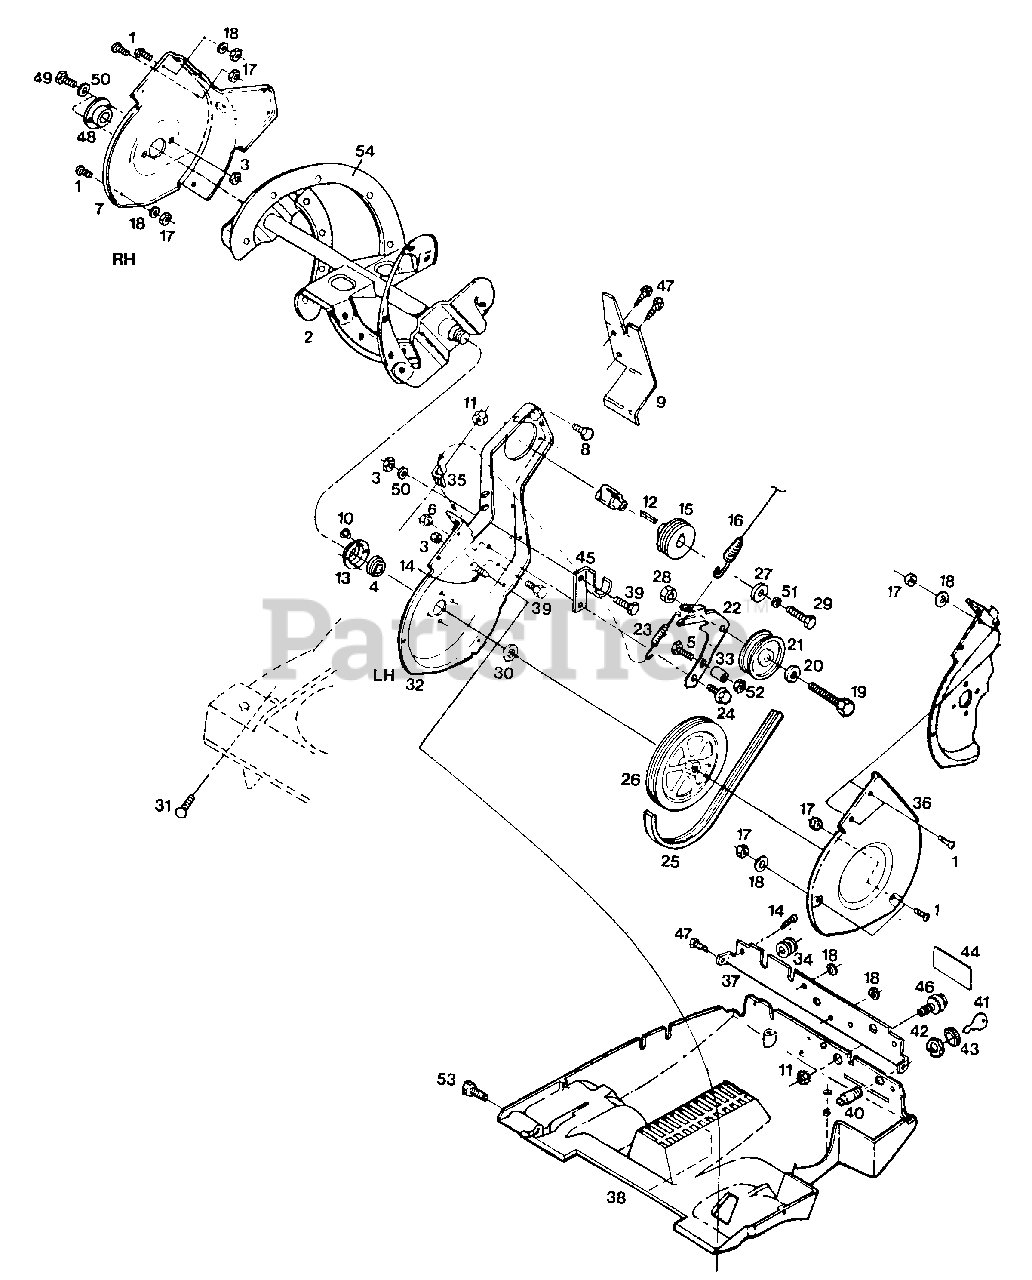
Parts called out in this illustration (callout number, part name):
1	SCREW - Phillips #10 - 24 x 5/8"
2	AUGER - Assembly
3	NUT - 1/4 - 20 Nylock
4	BEARING
5	BOLT - Hex 1/4 - 20 x 1
6	NUT, 5/16-18 Nylock
7	FRAME - Right Side
8	BOLT - Hex 5/16 - 24 x 5/8
9	SHIELD - Belt
10	RIVET - 1/4
11	NUT - Keps 1/4 - 20
12	KEY - 1865 Sq. x 1
13	RETAINER - Bearing
14	SCREW - H.W.H. Tap #10 - 24 x 3/4
15	PULLEY - Drive
16	CABLE - Auger Control
17	NUT - #10 - 24
18	WASHER - Retaining
19	BOLT - Hex 3/8 - 16 x 1-1/2
20	WASHER - Flat 3/8
21	PULLEY - Idler
22	ARM - Idler
23	SPRING - Extension
24	BOLT - Idler Pivot
25	BELT - Drive
26	PULLEY - Drive
27	WASHER - Flat
28	NUT - Serrated Flange Lock 3/8
29	BOLT - Hex 5/16 - 24 x 7/8 Gr. 5
31	BOLT - Carriage 1/4 - 20 x 3/4
32	FRAME - Left Side
33	ROLLER - Belt Stop
34	GROMMET - Metal
35	CLIP - Spring
36	GUARD - Belt
37	BRACKET - Control Panel
38	COWLING - Lower, Electric Start
39	BOLT - Hex 1/4 - 20 x 3/4
40	SWITCH - Ignition
41	KEY - Ignition
42	NUT - Hex Ignition Switch 5/8 - 32
43	BOOT - Ignition Switch
44	DECAL - Choke
45	BRACKET - Belt
46	PRIMER - Bulb
47	SCREW - H.W.H. Tap #10 - 24 x 1/2
48	BEARING - Plastic
49	BOLT - Hex 1/4 - 20 x 7/8 Gr. 5
50	WASHER - Flat 1/4
51	WASHER - Split Lock 5/16
52	NUT - 1/4 - 20 Center Lock
53	SCREW - Hex 1/4 - 20 x 5/8
54	KIT - Auger Flighting
